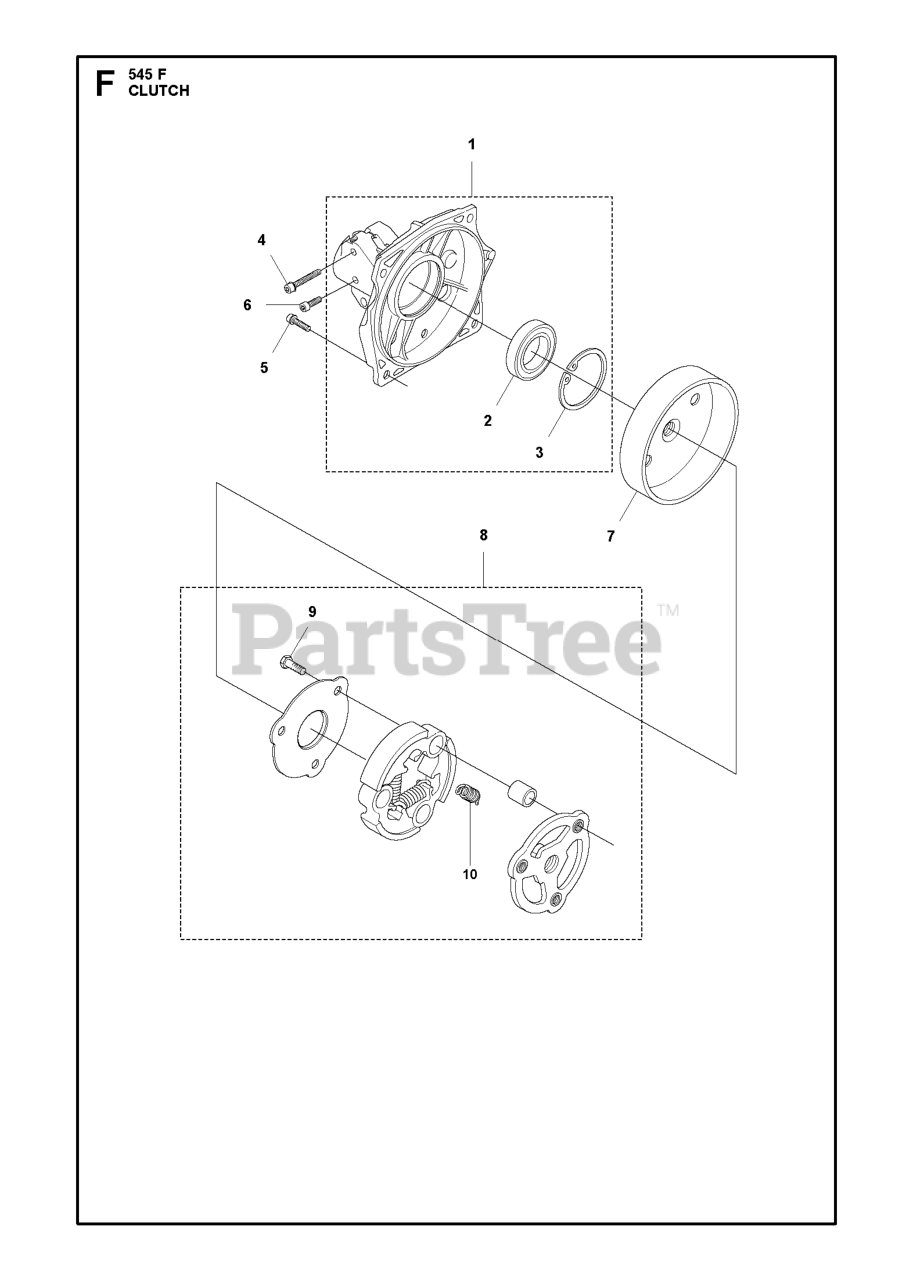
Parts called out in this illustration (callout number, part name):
1	CLUTCH COVER
2	BALL BEARING 6202-2RS1
3	RETAINING RING SGH 35
6	SCREW MC6LS 5X12
7	CLUTCH DRUM ASSM.
10	CLUTCH SPRING
